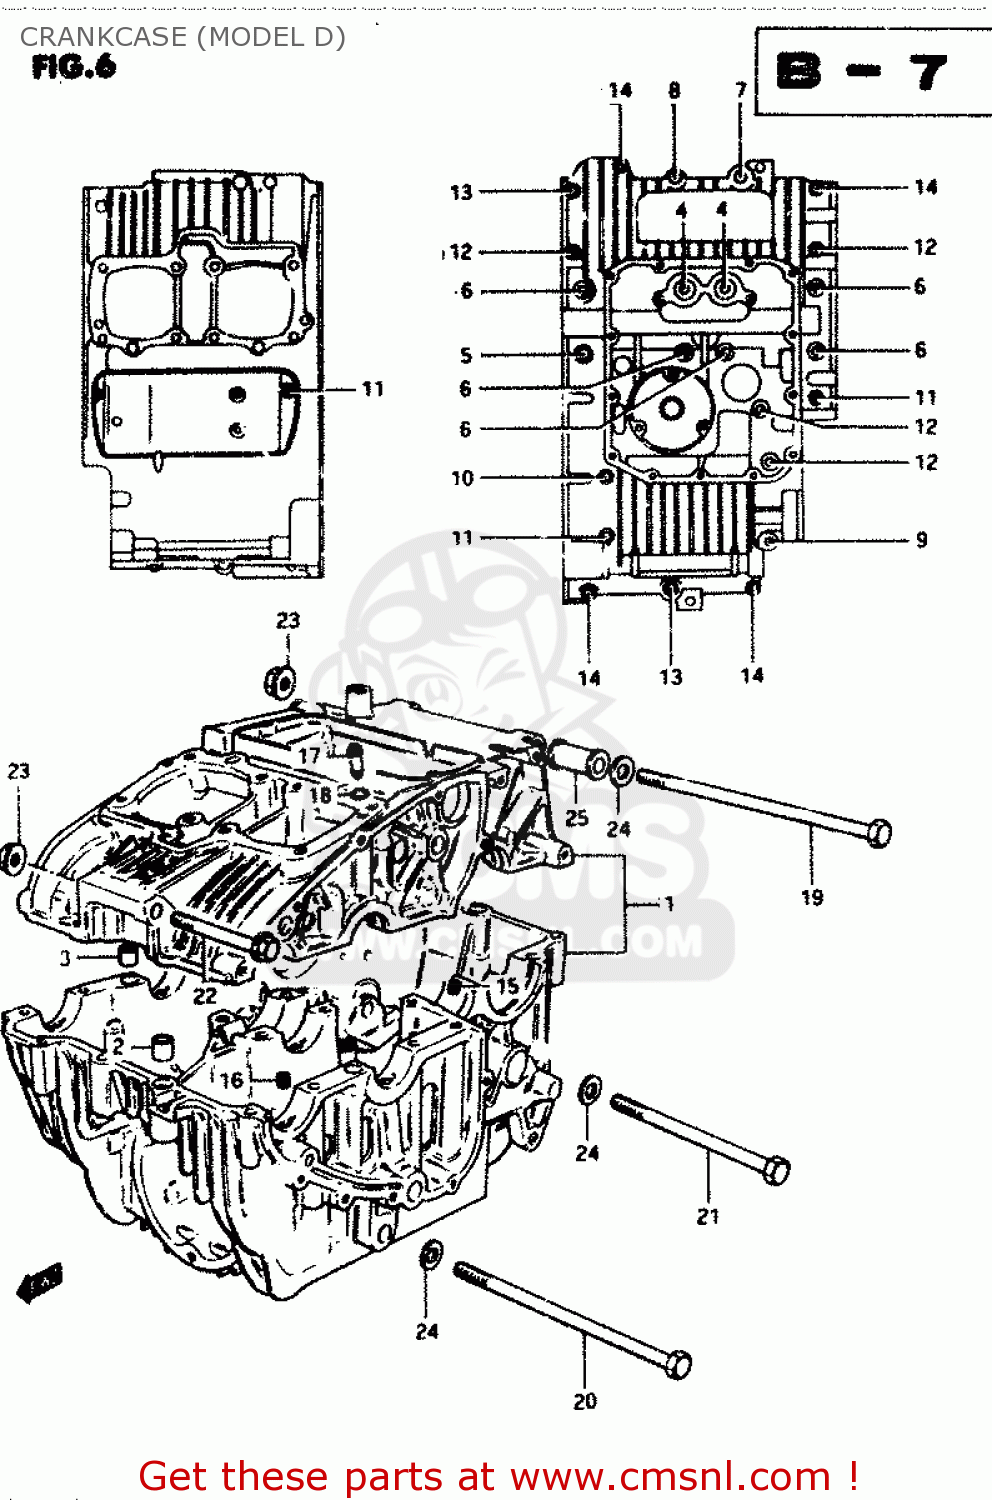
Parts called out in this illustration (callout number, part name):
1	CRANKCASE SET
2	PIN(10.4X13X22)
3	PIN (11X20)(SUS)
4	BOLT
5	BOLT
6	BOLT
7	BOLT (8X65)
8	BOLT (8X50)
9	BOLT (8X40)
10	BOLT(6X125)
11	BOLT(6X105)
12	BOLT (6X90)
13	BOLT ,6X60
14	BOLT (6X45)
15	JET,AIR(100)
16	JET,AIR
17	JET,AIR
18	O RING(D:1.05,ID:3.1)
19	BOLT
20	BOLT
21	BOLT
22	BOLT (10X90)
23	NUT 10MM
24	WASHER
25	SPACER,ENGINE MOUNT
